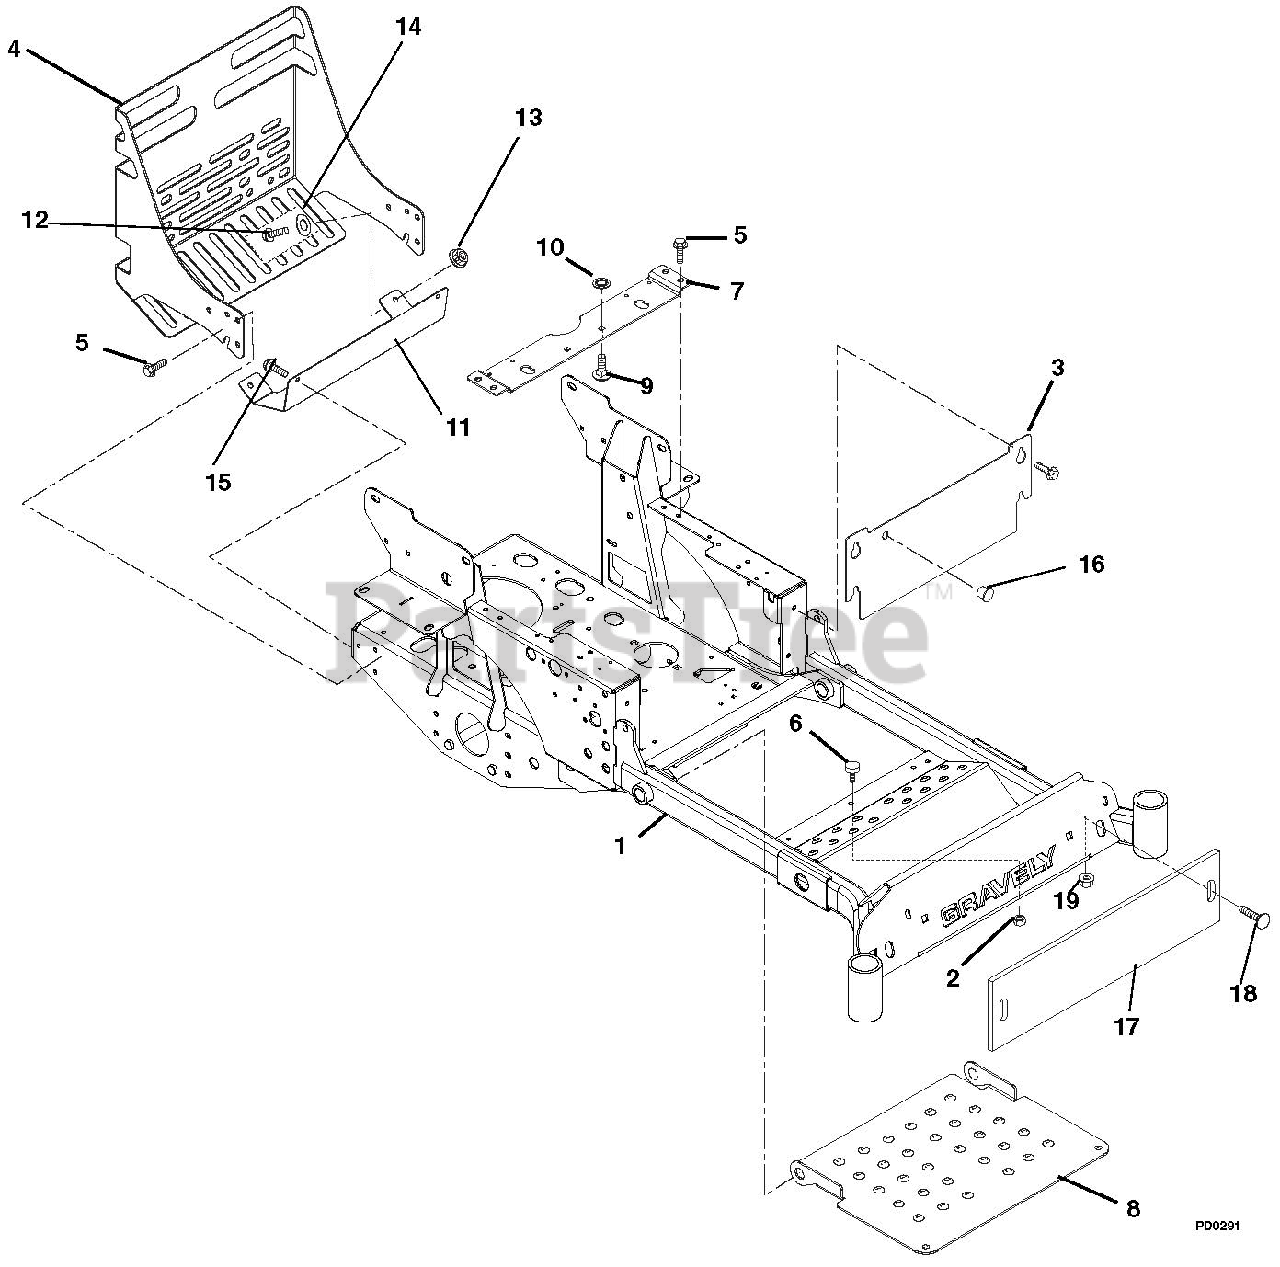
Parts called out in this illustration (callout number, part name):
1	Frame, Compact-Z
2	Nut, Spin Lock Flange .312-18
3	Access Panel
4	Bumper, Rear
5	Screw, Tapping .38-16 x .75 Hex Washer Head
6	Bumper, Rubber
7	Seat Support
8	Panel, Inspection
9	Bolt, Round Head Square Short Neck .31-18 x .75 Grade 5
10	Nut, Push .312
11	Heat Shield, Compact Z
12	Bolt, Hex .38-16 x .75 Grade 5
13	Nut, Nyloc Flange .38-16
14	Washer, Flat Steel .438 x 1.00 x .083
15	Screw, Tapping .38-16 x .50 Hex Washer Head
16	Plug, Hole .56
17	Counterwieght CZ Front- Red
18	Bolt, Round Head Square Neck .50-13 x 2.50 Grade 5
19	Nut .50-13 Nyloc Flange
